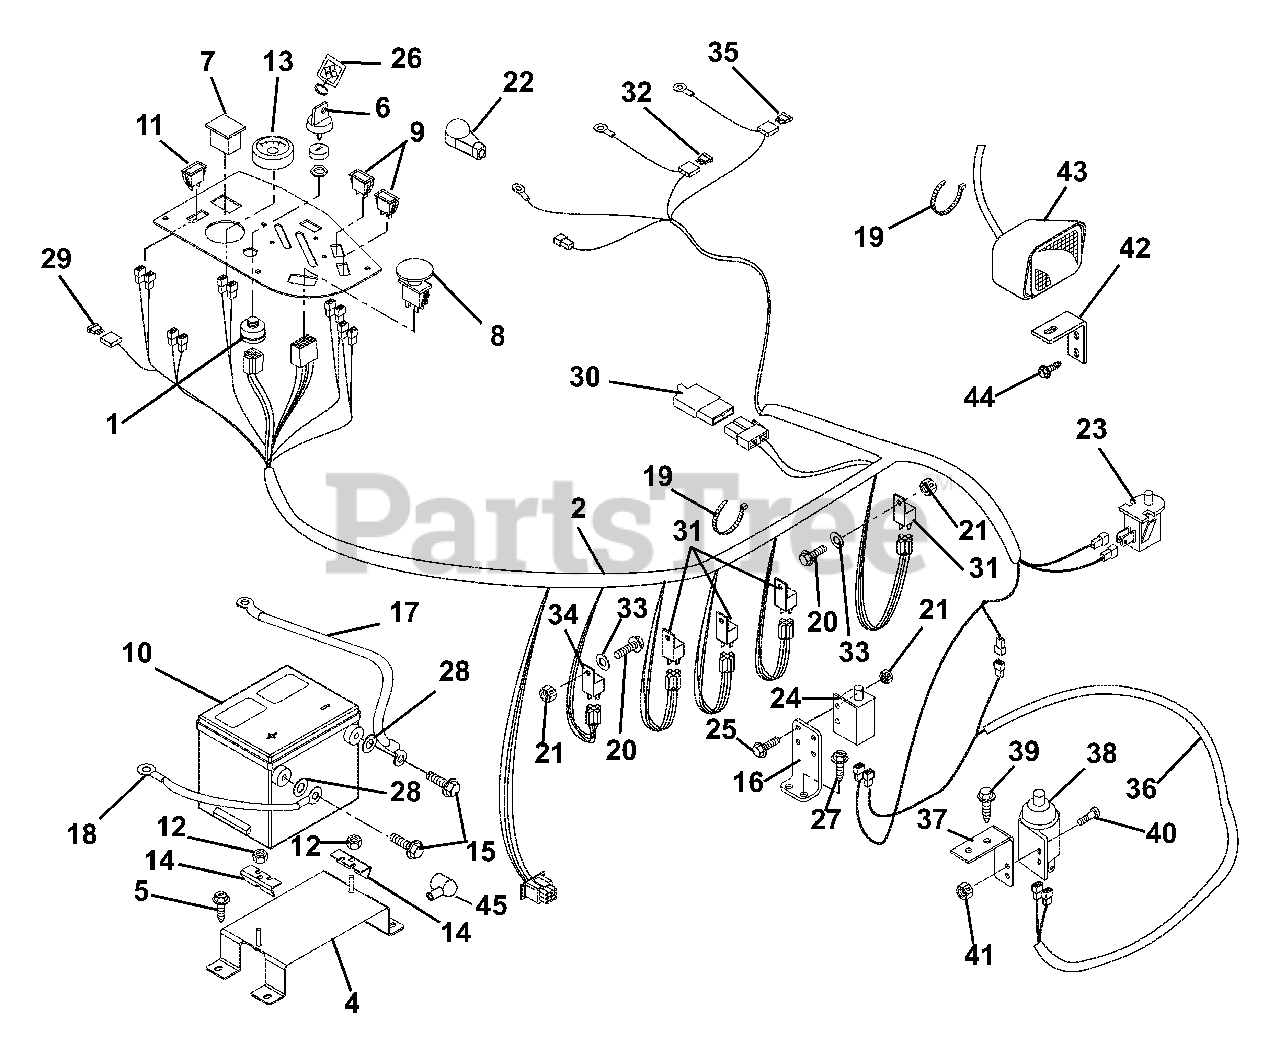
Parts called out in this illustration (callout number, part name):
1	Switch, Ignition (Diesel)
1	Switch, Ignition
2	Harness, Wiring (Diesel)
3	Harness, Wire (Gas)
4	Weldment, Battery Support
5	Screw-Tapping .38-16 x .75 Hex Washer Head
6	Key-with Cap
6	Ignition Key Set
8	Switch-Clutch With Retainer Ring
9	Light-Indicator Kit
10	Battery with Tube
11	Switch, Light
12	Nut-Locking-Top-Flange .31-18
13	Gauge, Temperature
14	Bracket, Battery Hold-Down
15	Bolt-Hex .25-20 x .75 Grade 5
16	Mount, Safety Switch
17	Positive Cable
18	Cable, Negative Battery
18	Ground Cable
19	Cable Tie
20	Screw-Machine 10-24 x .75 Hex Washer Head
21	Nut-Locking-Nylon 10-24 With Insert
22	Eyelet Terminal Boot
23	Switch, Snap Mounting (N.O.)
24	Switch-Single Pole
25	Screw-Machine 10-24 x .75 Hex Washer Head
26	Key Chain
27	Screw-Tapping .25-20 x .50 Hex Washer Head
28	Washer-Flat-Steel .406 x 1.00 x ..083
29	Fuse, 15 Amp
30	Diode, Connector Shell
31	Relay
32	Fuse, 30 Amp
33	Washer-Flat-Steel .25 x .562 x .049
35	Fuse, 50 AMP (Maxi Fuse)
35	Fuse, 25 Amp
36	Harness, Wire Adapter CE
37	Mount- Switch
38	Switch-Single Pole (N.O.) with Cover
39	Screw-Tapping .31-18 x .50 Hex Washer Head
40	Screw-Machine 10-24 x .75 Hex Washer Head
41	Nut-Locking-Nylon 10-24 with Insert
42	Bracket, Headlight Mounting
43	Headlight
44	Screw-Tapping .38-16 x .50 Hex Washer Head
45	Boot, Eyelet Terminal
